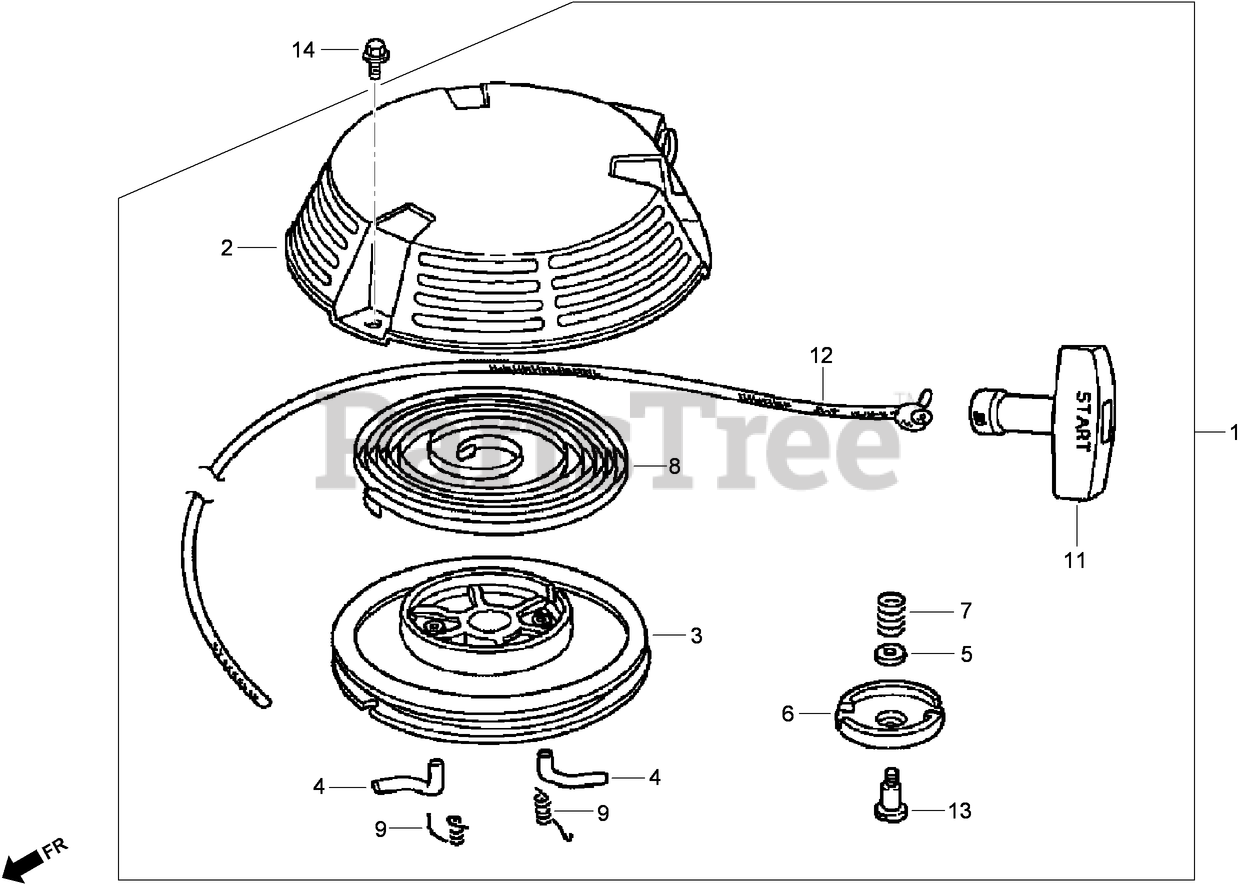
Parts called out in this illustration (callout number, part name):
1	RECOIL STARTER ASM (N H1) (BLACK)
2	CASE-STARTER, RECOIL (N H1) (BLACK)
3	REEL-STARTER, RECOIL (BLACK)
4	RATCHET-STARTER
5	PLATE-FRICTION
6	GUIDE-RATCHET
7	SPRING-FRICTION
8	SPRING-STARTER, RECOIL
9	SPRING-RETURN
11	GRIP-STARTER
12	ROPE-STARTER, RECOIL
13	SCREW-SETTING
14	BOLT-FLANGE (6X8)
